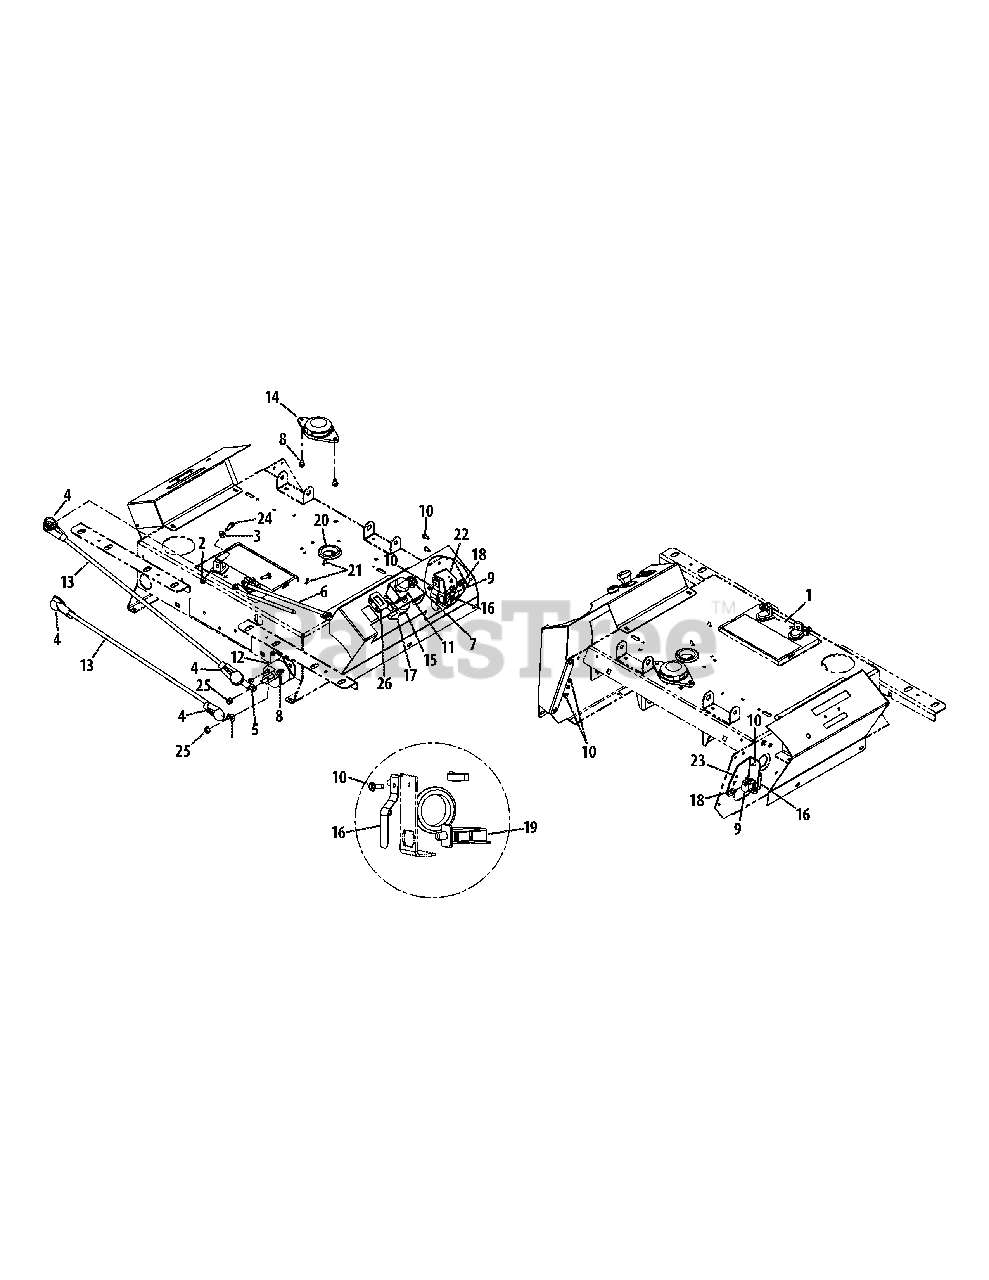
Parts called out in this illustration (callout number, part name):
2	Nylock Nut, 1/4-20
3	Washer, .281 x .625 x .063
4	Boot Terminal, 1.00 x 2.50
5	Nylock Nut, #10-32
6	Battery Cable
7	Nut, 5/8-32
8	Hex Flange Screw, 1/4-20 x .500
9	Switch
10	Flange Screw, #10-24 x .500
11	PTO Switch
12	Solenoid
13	Battery Cable
14	Seat Switch
15	Ignition Switch
16	Renovator Spring
17	PTO Bracket
18	Nut, #10-24
19	Delta Switch
20	Grommet, 1/8 x 1.5 x 2.13
21	Electric CDT Clip
22	RH Deck Switch Mount Bracket
23	LH Deck Switch Mount Bracket
24	Hex Screw, 1/4-20 x .75
25	Hex Lock Nut, 5/16-18
26	Hour Meter
